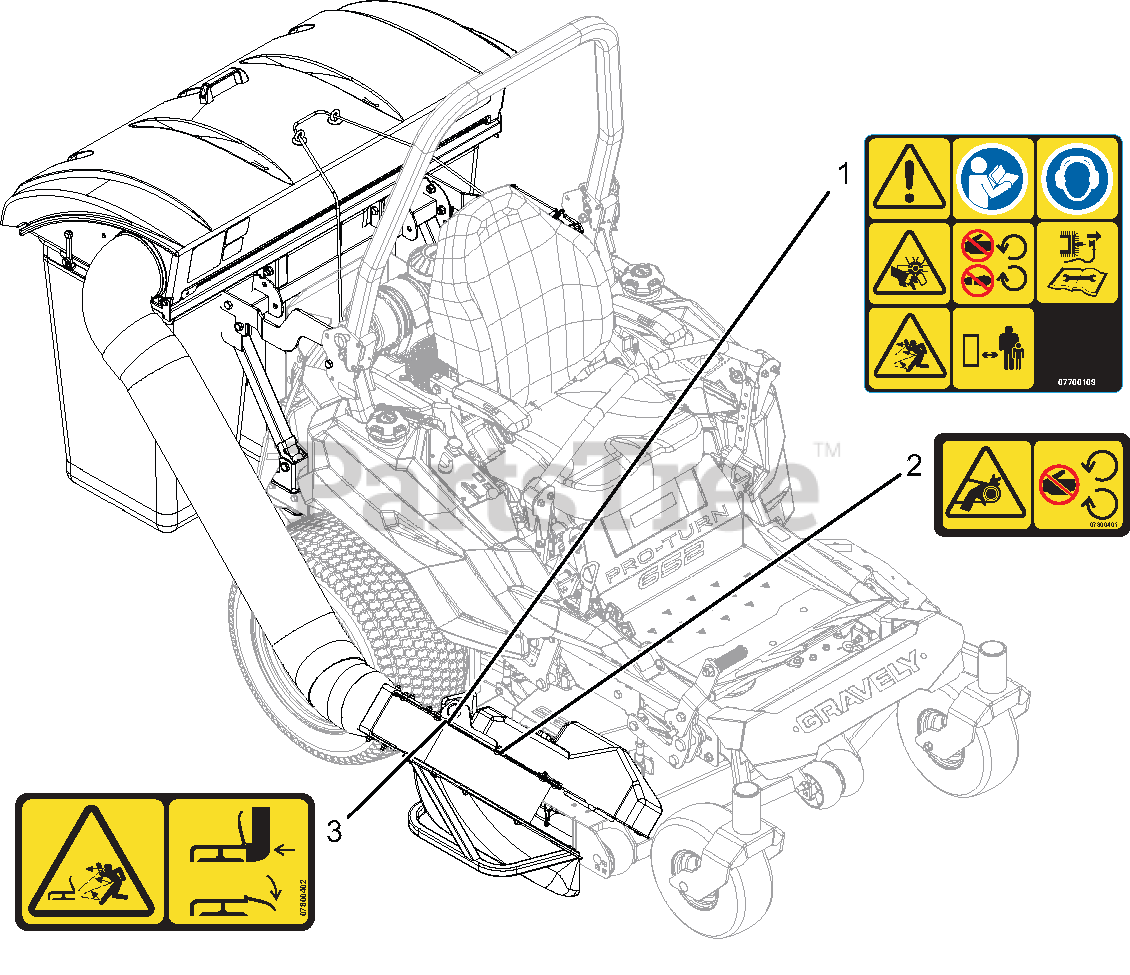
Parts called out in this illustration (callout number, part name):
1	DECAL,VAC WARNING ISO
2	DECAL, SAFETY - GUARDING
3	DECAL, SAFETY - DECK GUARDING
